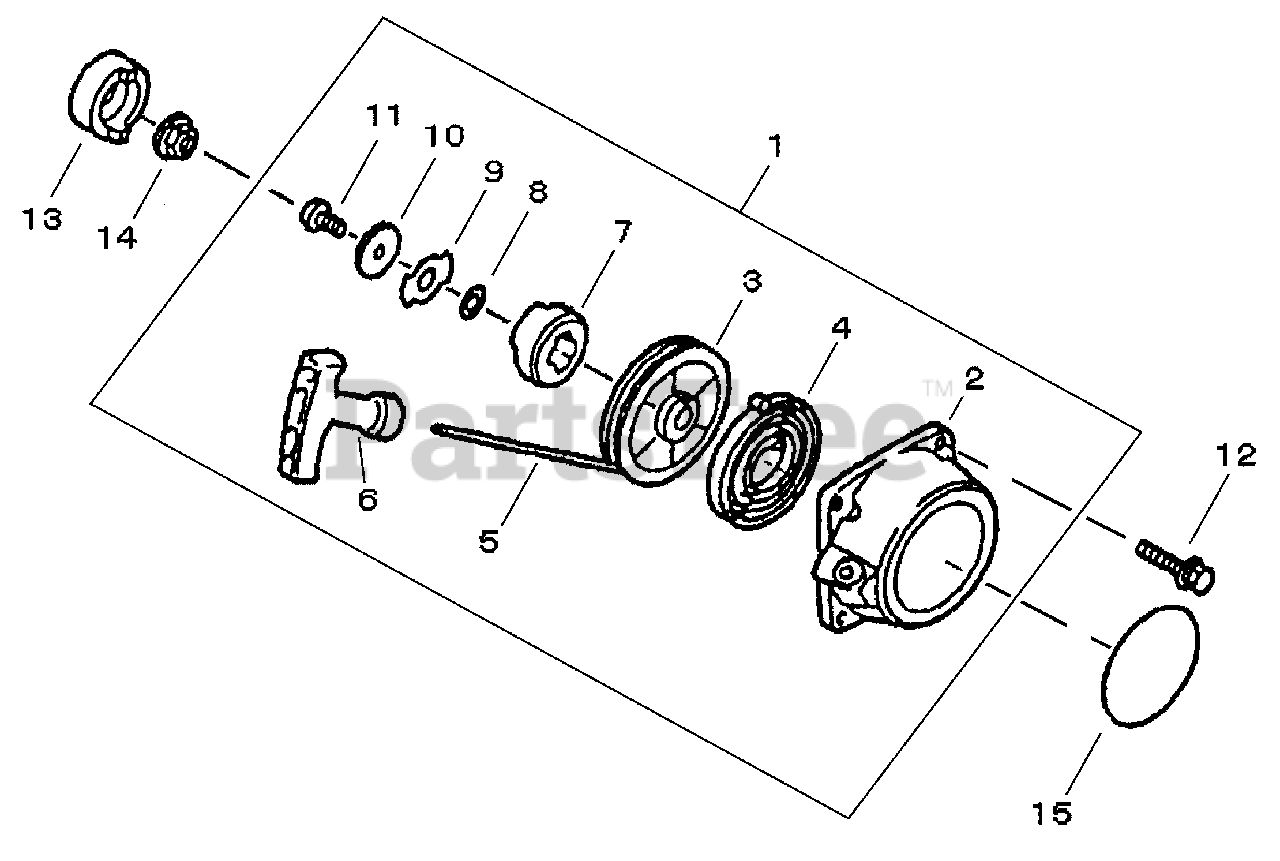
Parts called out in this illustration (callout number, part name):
1	STARTER ASSY, RECOIL
2	CASE, RECOIL STARTER
3	REEL
4	SPRING, RECOIL
6	GRIP, STARTER
7	CAM
9	RETAINER
11	SCREW M8×1.25
12	BOLT M5×20
13	PULLEY, STARTER
14	NUT, FLANGE M10
15	LABEL, TRADE
